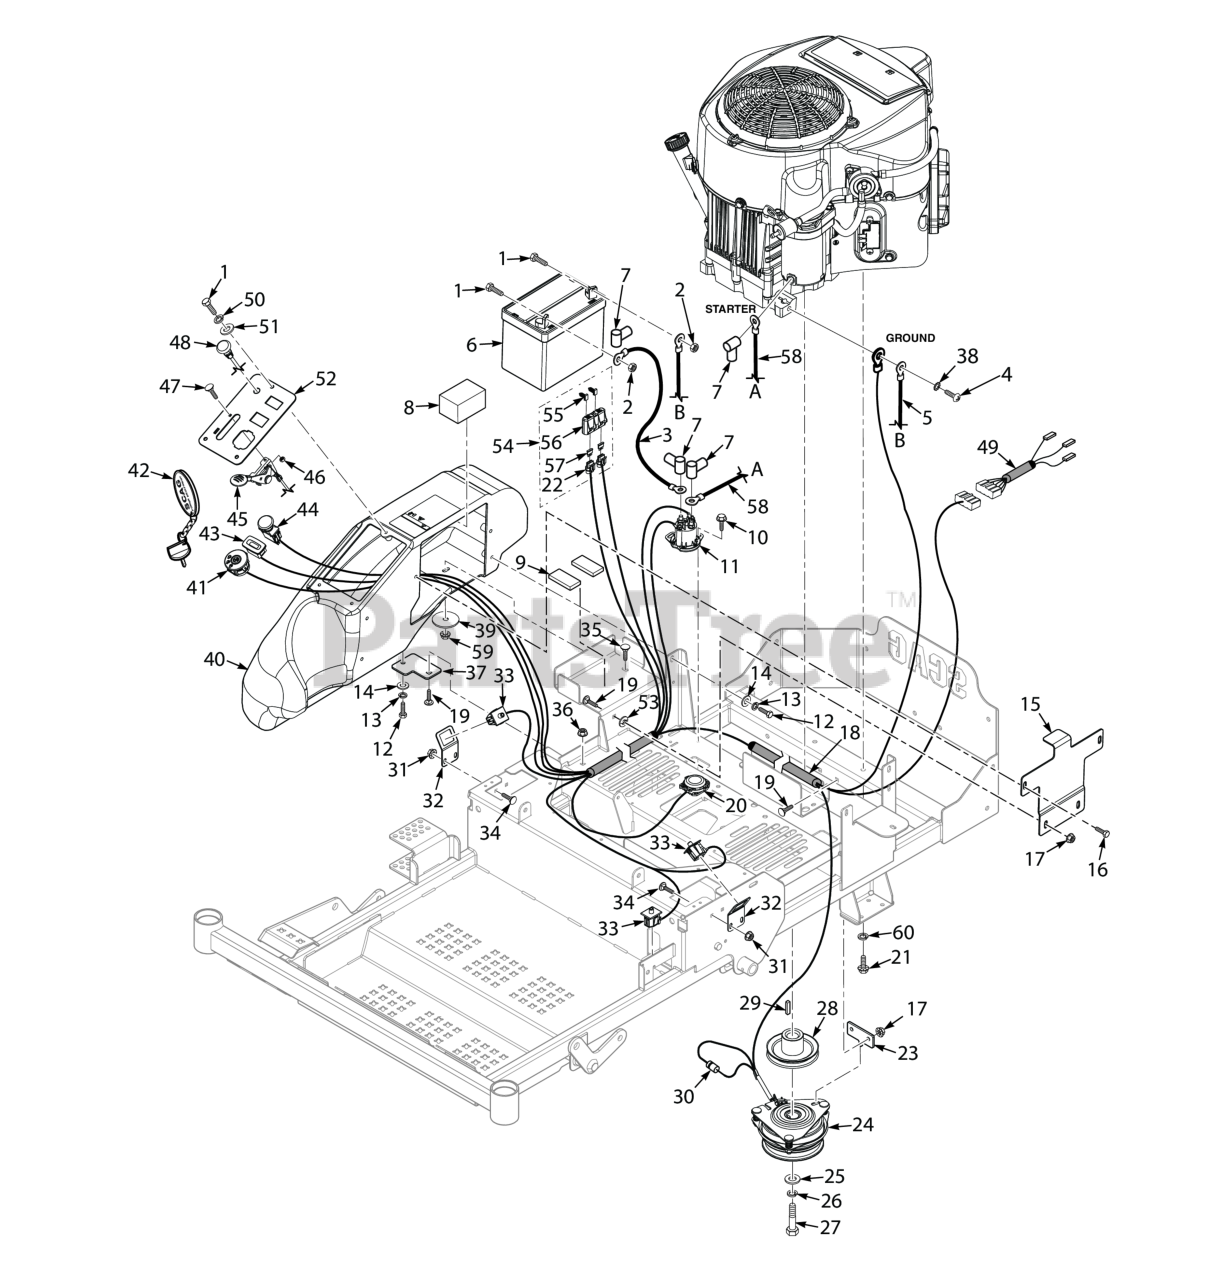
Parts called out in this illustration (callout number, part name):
1	Bolt, Hex Head 1/4-20 x .5" Battery, (Not Available Through Scag)
2	Nut, 1/4 - 20 Hex
3	Battery Cable, 18" Red w/Braid (25KA, 26DFI, 31DFI) - Kawasaki
4	Bolt, Hex Head M8 - 1.25 x 16 (48V / 52V)
5	Battery Cable, 31-1/2" Black (25KA, 26DFI, 31DFI) - Kawasaki
6	Battery, 12v - 230CCA
7	RUBBER BOOT
8	Pad, Battery - Rubber
9	Pad, Battery - Rubber
10	Screw, Self-Tapping 1/4-20 x 3/4
11	Solenoid, Sealed (Briggs & Stratton)
12	BOLT, SERRATED FLANGE HEX HEAD 5/16-18 X 3/4"
13	Lockwasher, 5/16 (.317 x .586 x .078) Helical Spring
14	Flatwasher, 5/16-.375 x .875 x .083 (35BV & 37BV-EFI)
16	CAP SCREW, 5/16-18 X 1/2" SERRATED FLANGE HEX
17	Nut, Flange Head Elastic Stop 5/16-18
18	Wire Harness
19	Bolt, 5/16-18 x .75 RHSN Carriage
20	Switch, Double Pole - Twist
21	Bolt, Hex Head 3/8-16 x 1-1/4", Kawasaki FX / FS
22	Fuse Holder Assembly
23	Plate, Anti-Rotation
24	Electric Clutch Assembly
25	Flatwasher, 7/16-.469 x 1.75 x .25 (48, 52)
26	Lockwasher, 7/16� Spring
27	Bolt, Hex Head 7/16-20 x 3¼" w/Patch
28	Pulley, 4-1/2" - 1" Bore
29	Key, 1/4 x 1/4 x 1.25" Pulley Mtg.
30	Diode, 600V 6 Amp
31	Nut, Flanged Elastic Stop 1/4-20
32	Bracket, Switch
33	Switch, Double Pole - Plunger
34	Serr. Fl. Hex Head CPSCR, 1/4-20 x 3/4"
35	Bolt, Carriage 5/16-18x1" (large frame units only)
36	Nut, Serrated Flange 5/16-18 (Right Front Engine Mounting, Briggs and Kohler Only)
37	Mounting Bracket, Fuel Tanks Front
38	Lockwasher, 5/16" Ext. Tooth (Kohler x1)
39	Flatwasher, 3/8-.406 x 2.25" x .1875
40	Console Tank, SZL
41	Ignition Switch
42	Key, Assembly w/Fob
43	Hour Meter, Inductive
44	Switch, PTO - 10 Amp
45	Throttle Control, Kawasaki
46	Nut, Elastic Stop #10-24
47	Bolt, Carriage #10-24 x 1/2"
48	Choke Control, Kawasaki
50	Lockwasher, 1/4� Spring
51	Flatwasher, 1/4" (.312 x .750 x .065")
52	Instrument Panel w/Decal
53	Nut, Push-On 5/16-18
54	Double Fuse Assy.
55	Clip, Fuse Holder
56	Cover, Sealed Double
57	FUSE, 20 AMP BLADE TYPE AUTOMOTIVE
58	Battery Cable, 18" Red w/Braid (25KA, 26DFI, 31DFI) - Kawasaki
59	HEX NUT, ELASTIC STOP LOCK, 5/16-18
60	Lockwasher, 3/8" Spring, Kawasaki FX / FS
